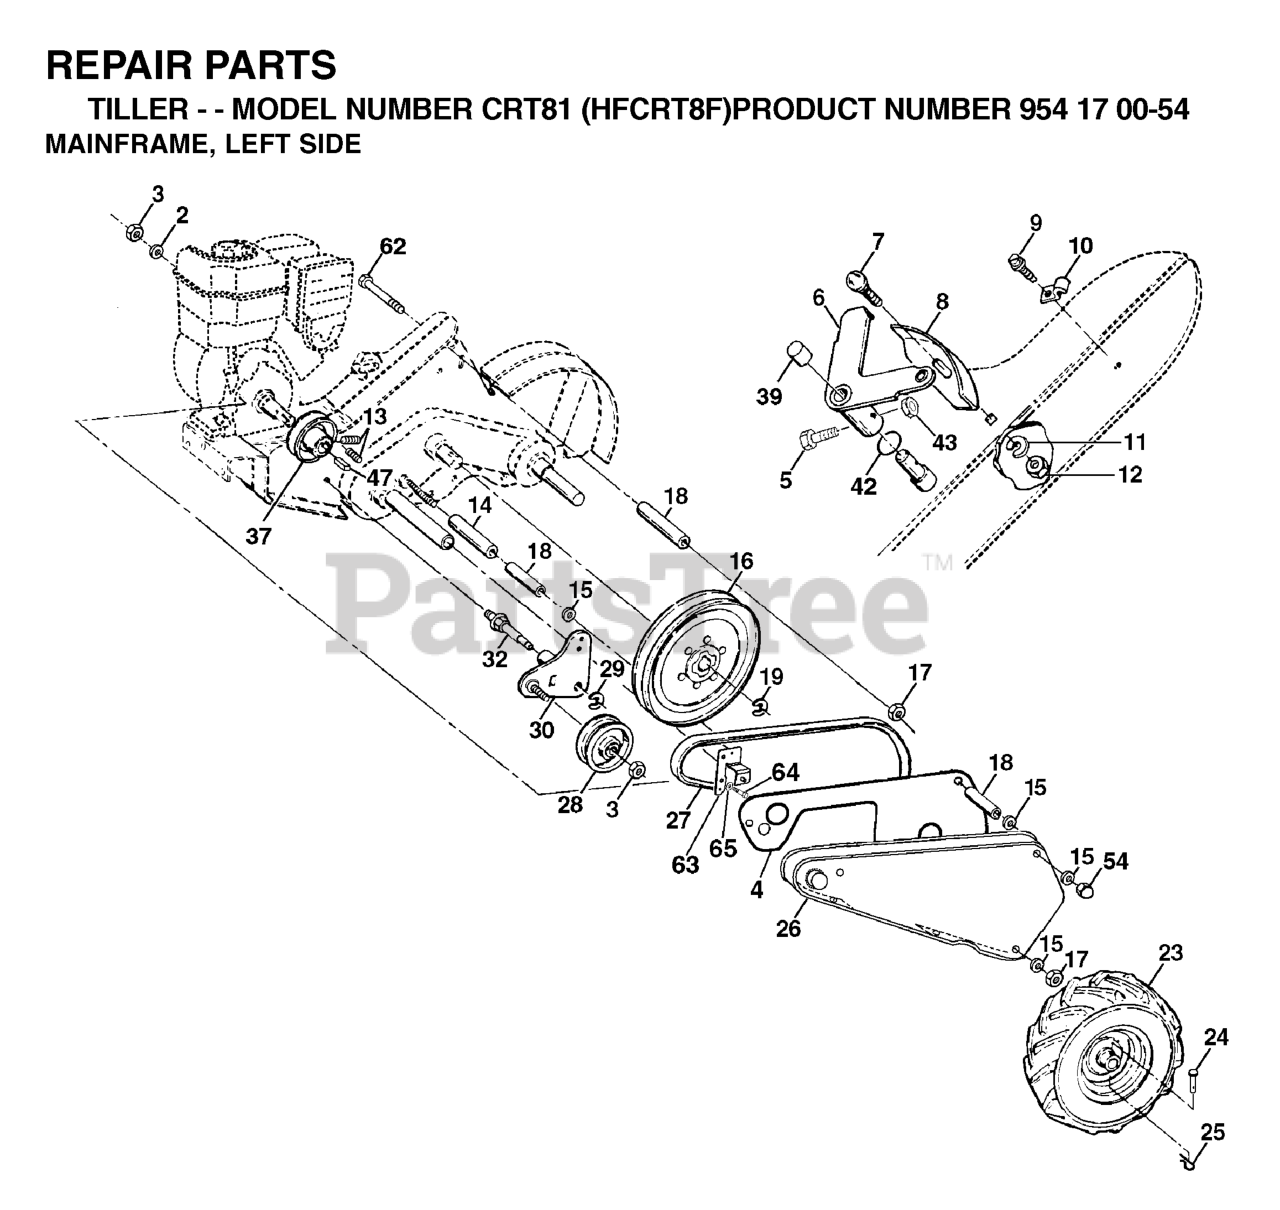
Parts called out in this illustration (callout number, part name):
2	WASHER, LOCK 3/8
3	NUT.HEX.3/8-16UNC
4	Shield, Inner Belt Guard RT
5	SCREW, SHIFT LEVER
6	LEVER ASM CRT
8	PANEL.INDICATOR.SHIFT.BLACK
9	TAPPING SCREW
10	CONDUIT.CLIP.PLATED
11	LOCKWASHER
12	NUT
14	SPACER-SPLIT.327 X .42
15	WASHER
16	SHEAVE, TRANSMISSION
18	SPACER SPLIT
19	RETAINING RING LT
23	TIRE.16X4-8.CHEVRON.TILLER
24	RIVET,DRILLED
26	FOOTREST.PNT.LH
27	BELT, DRIVE
28	PULLEY-IDLER TI
30	BRACKET.ASM.IDLER.BLACK
32	SHAFT, IDLER ARM
37	SHEAVE, ENGINE
39	CAP.PLUNGER.BLACK
47	KEY, SQUARE
62	BOLT 5/16-18X4 1/2
63	Bracket Asm Guard
65	Washer 11/32 x 3/4 x 14 Gauge
